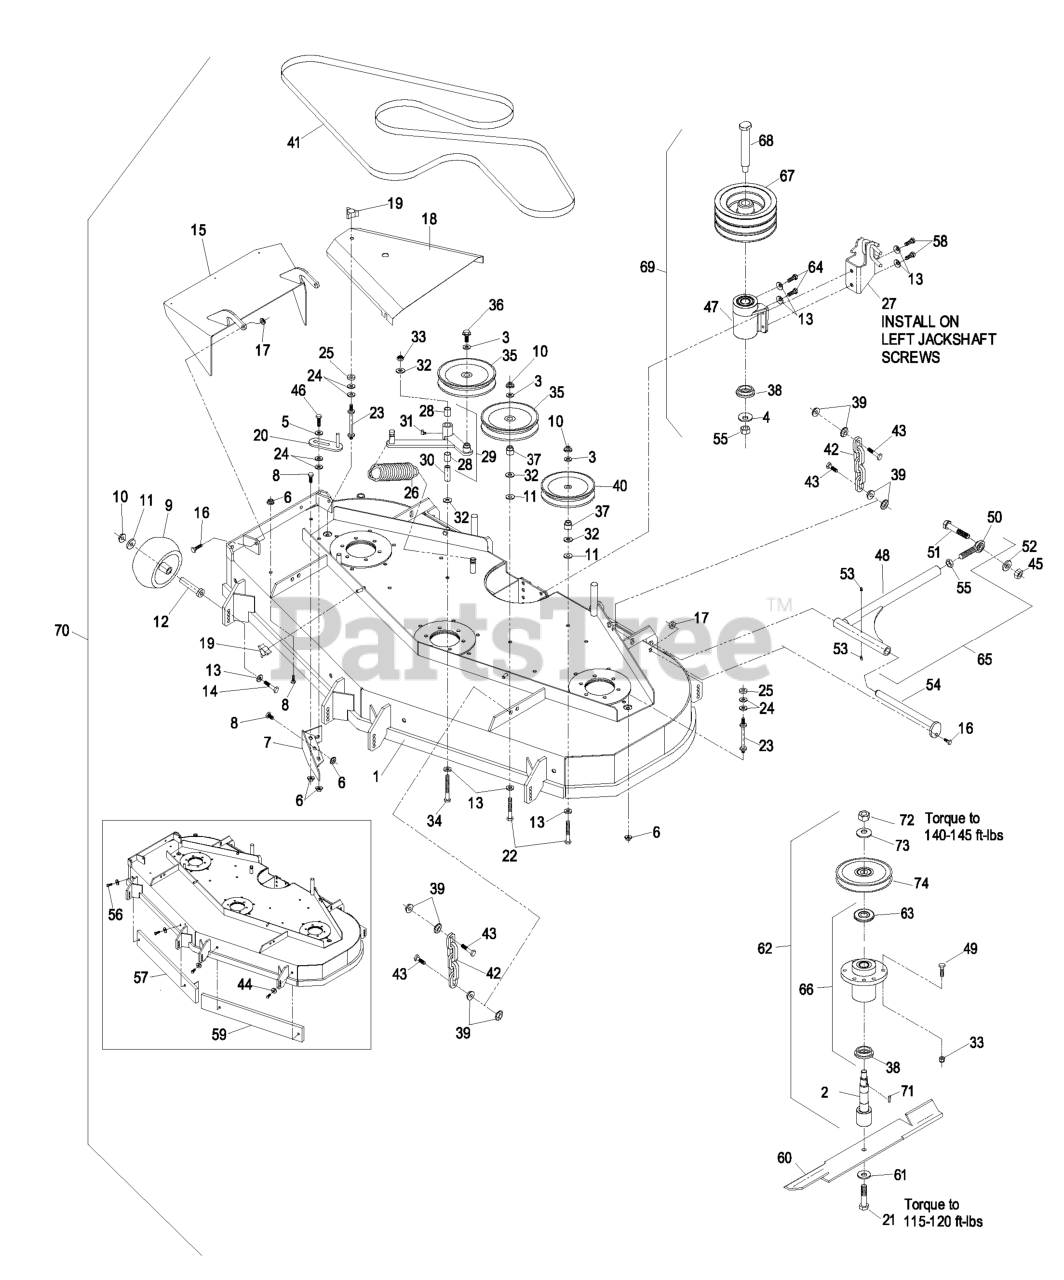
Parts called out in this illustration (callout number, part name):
1	ASM,DECK W/DECALS XP604
2	SPINDLE,SHORT
3	WASHER-FLAT
4	WASHER-SPRING
5	WASHER-SPRING
7	WLD,BAFFLE DISCHARGE
8	SCREW-HH
9	ROLLER-SCALP, ANTI
10	NUT-HHF, WHIZ
12	BUSHING-ROLLER
13	WASHER-BELLEVILLE
14	SCREW-HH
16	SCREW-HH
17	NUT-LOCK, NI
18	SHIELD,BELT
19	KNOB-3 PRONG
20	GUIDE-BELT
21	SCREW-CAP
22	SCREW-HH
23	STUD-SHIELD, BELT (SHORT)
24	WASHER-FLAT
28	SLEEVE-BEARING
30	BUSHING
31	FITTING-GREASE, 90 DEG
32	WASHER-FLAT
33	NUT-LOCK, NI
34	SCREW-HH
36	SCREW-HHF
37	BUSHING-IDLER
38	SPACER-GUARD, BOTTOM
40	PULLEY-IDLER
41	BELT,BLADE DRIVE
42	CHAIN-LIFT, DECK
43	SCREW-HH
44	WASHER-SPRING
45	NUT-HEX
46	SCREW-HH
49	SCREW-HH
50	BALLJOINT-SPHERICAL
51	SCREW-HH
52	WASHER-LOCK
53	FITTING-GREASE
54	PIN-STRUT
55	NUT-HEX
56	SCREW-HH
57	WEIGHT BAR ASM
58	SCREW-HH
61	WASHER-BLADE BOLT, HEAVY
63	GUARD-BEARING, TOP
64	SCREW-HH
65	STRUT ASM
67	SHEAVE-JACKSHAFT
68	JACKSHAFT
69	ASM,JACKSHAFT
70	Complete Deck Assy
74	SHEAVE,BLADE DRIVE 6.30
